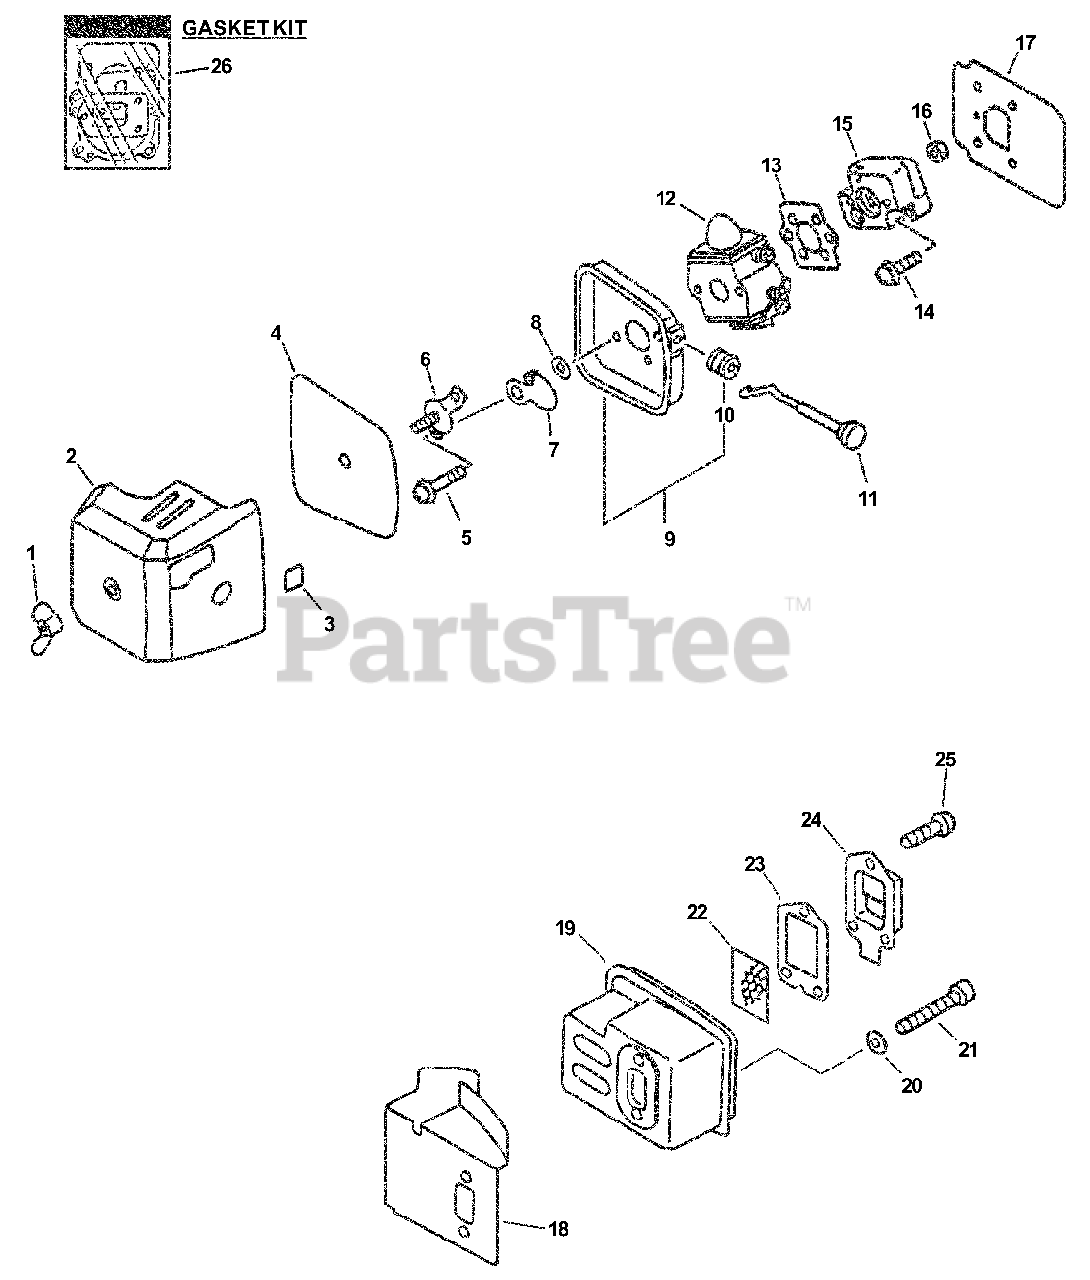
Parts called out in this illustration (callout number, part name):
1	WINGNUT - 6
2	COVER, AIR FILTER
3	LABEL, CHOKE
4	FILTER, AIR
5	SCREW 5×57
6	PLATE, PREVENT
7	SHUTTER, CHOKE
8	WASHER 5.2×8×0.8T
9	CASE, AIR FILTER
10	GROMMET, CHOKE
11	ROD, CHOKE
12	CARBURETOR - C1U-K54A
13	GASKET, INTAKE
14	SCREW 5×20
15	INSULATOR, INTAKE
16	NUT M5
17	HEAT SHIELD, INTAKE
18	HEAT SHIELD, EXHAUST
20	WASHER, FLAT 5.5×10×0.8
21	BOLT M5×50
22	SCREEN, SPARK ARRESTER
23	GASKET, EXHAUST
24	GUIDE, EXHAUST
25	SCREW 4×10
26	GASKET KIT
